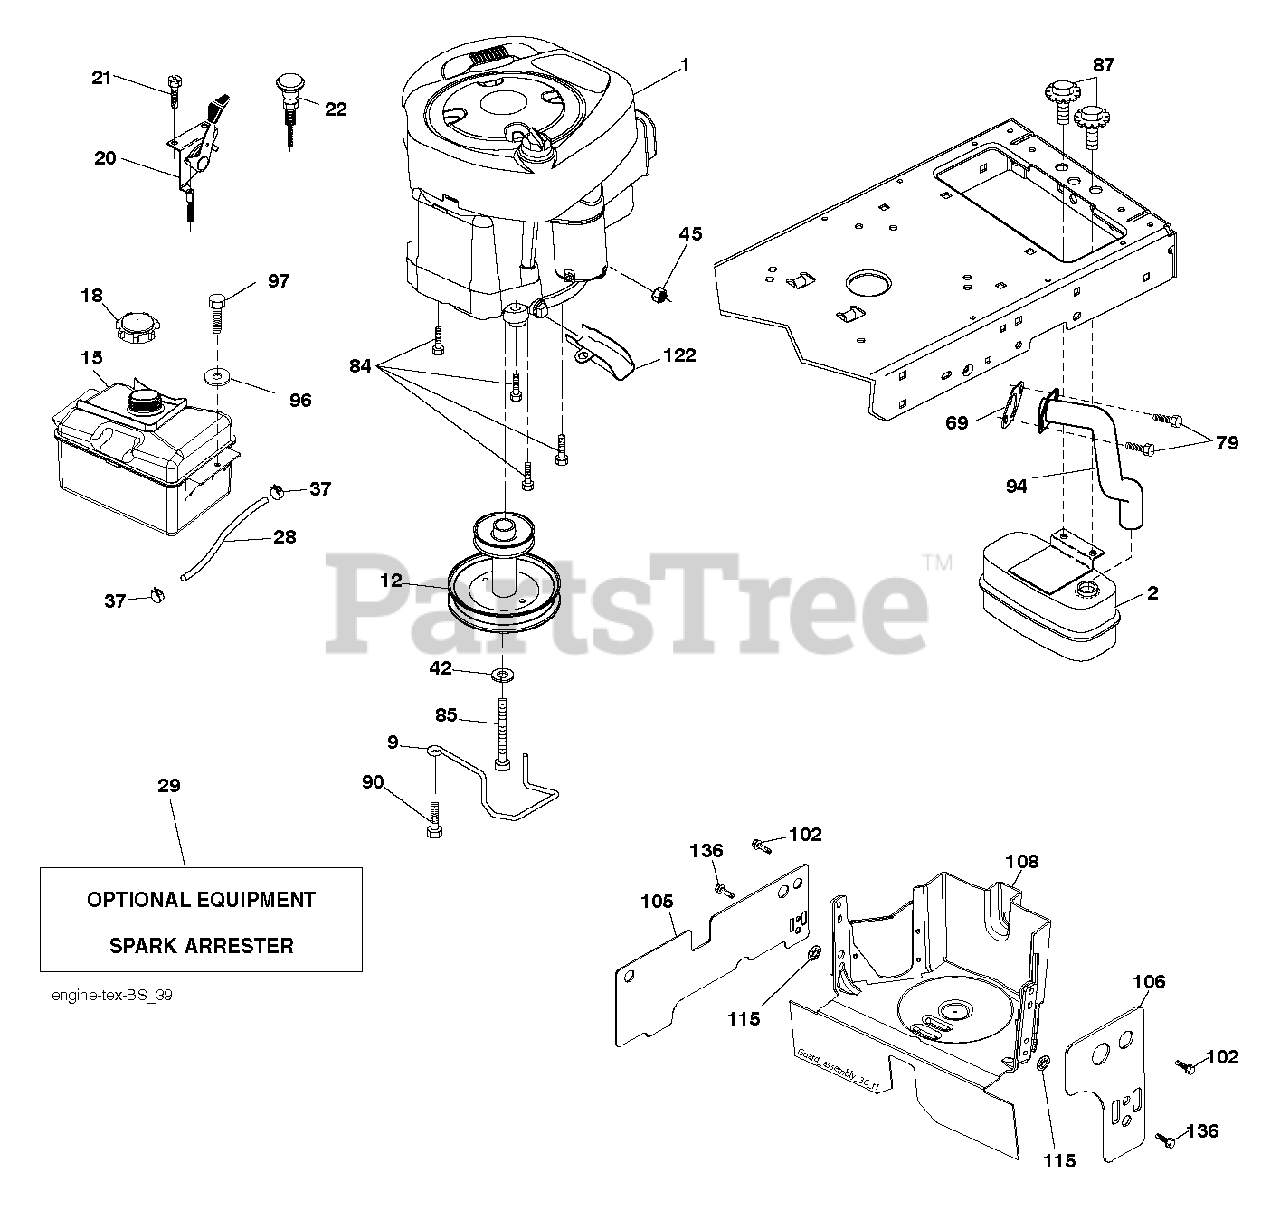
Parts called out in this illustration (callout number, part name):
2	Muffler, Single Cylinder Kohler/B&S
9	Belt Keeper, 4 25"2 Blt 431
12	PULLY ENGINE
18	CAP ASM.FUEL.2.25"FR.
20	CONTROL.TH/CK.C.
21	SCREW.#10 X 0.750.BOS THREAD
28	LINE.FUEL.20
29	ARRESTER SPARK (OPTIONAL)
37	HOSE CLAMP
42	LOCKWASHER
45	NUT
69	REPL BY 532 27 22-93
79	SCREW.SOCKET HD.5/16-1
84	SCREW.3/8-16
85	BOLT HEX 7/16-20X4-1/4"
87	BOLT, 5/16-18 X 1 3/4
90	SCREW 3/8-16X1
94	RP.EXHAUST.TUBE.B S.2
97	SCREW HEXWSHR 1/4-20X3/4
102	SCREW
115	PALNUT 1/4
122	EXTENSION DRAIN OIL
136	SCREW.1/4-20X5/8
